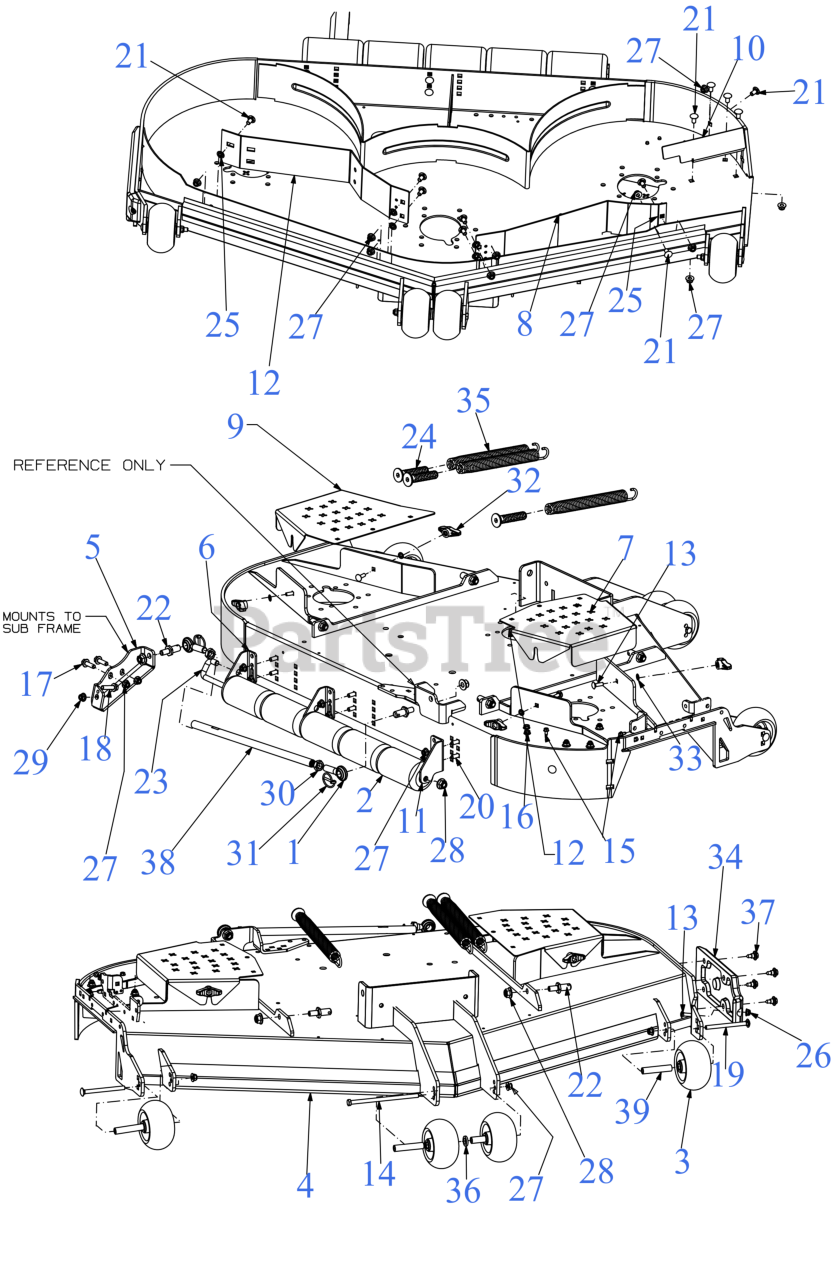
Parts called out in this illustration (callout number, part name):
1	MALE ROD END
2	ROLLER ASSEMBLY
3	5" DIA DECK WHEEL COMPLETE
3	WHEEL BUSHING
4	60" FAB DECK SHELL
5	STABILIZER MOUNTING BRACKET
6	REAR MOUNT BRACKET
7	DECK BELT COVER
8	DECK BAFFLE
9	BELT COVER
11	REAR ROLLER BRACKET (RH)
12	DECK BAFFLE
13	CARRIAGE BOLT 5/16-18 x 1.00
14	SCREW 3/8-16 x 7.25 GR5
15	SCREW 1/4-20 X.500
16	SCREW 5/16-18 x .500
17	SCREW 3/8-16 x 1.25 GR5
18	HEX HEAD BOLT (3/8-16:1.50 GR8)
19	CARRIAGE BOLT 3/8-16 x 4.25 GR5
20	CARRIAGE BOLT 3/8-16 x 1.00 GR5
21	CARRIAGE BOLT 3/8-16 x .75
23	REAR ROLLER PIN
24	SPRING INSERT SCREW
26	FLANGE LOCK NUT 5/16-18
29	LOCK NUT (3/8-16)
30	HEX JAM NUT 5/8-18
31	LYNCH PIN .1875
32	WING KNOB 5/16-18
34	DECK SKID PLATE (LH)
35	EXTENTION SPRING 1.20 x 11.35
36	FLAT WASHER .632X1.00X.16
37	SHOULDER SCREW .43X.29X5/16-18 TT
38	TUBE .565 X .750 X 18.75"LG
39	WHEEL SPACER .38ID x 3.04LG
